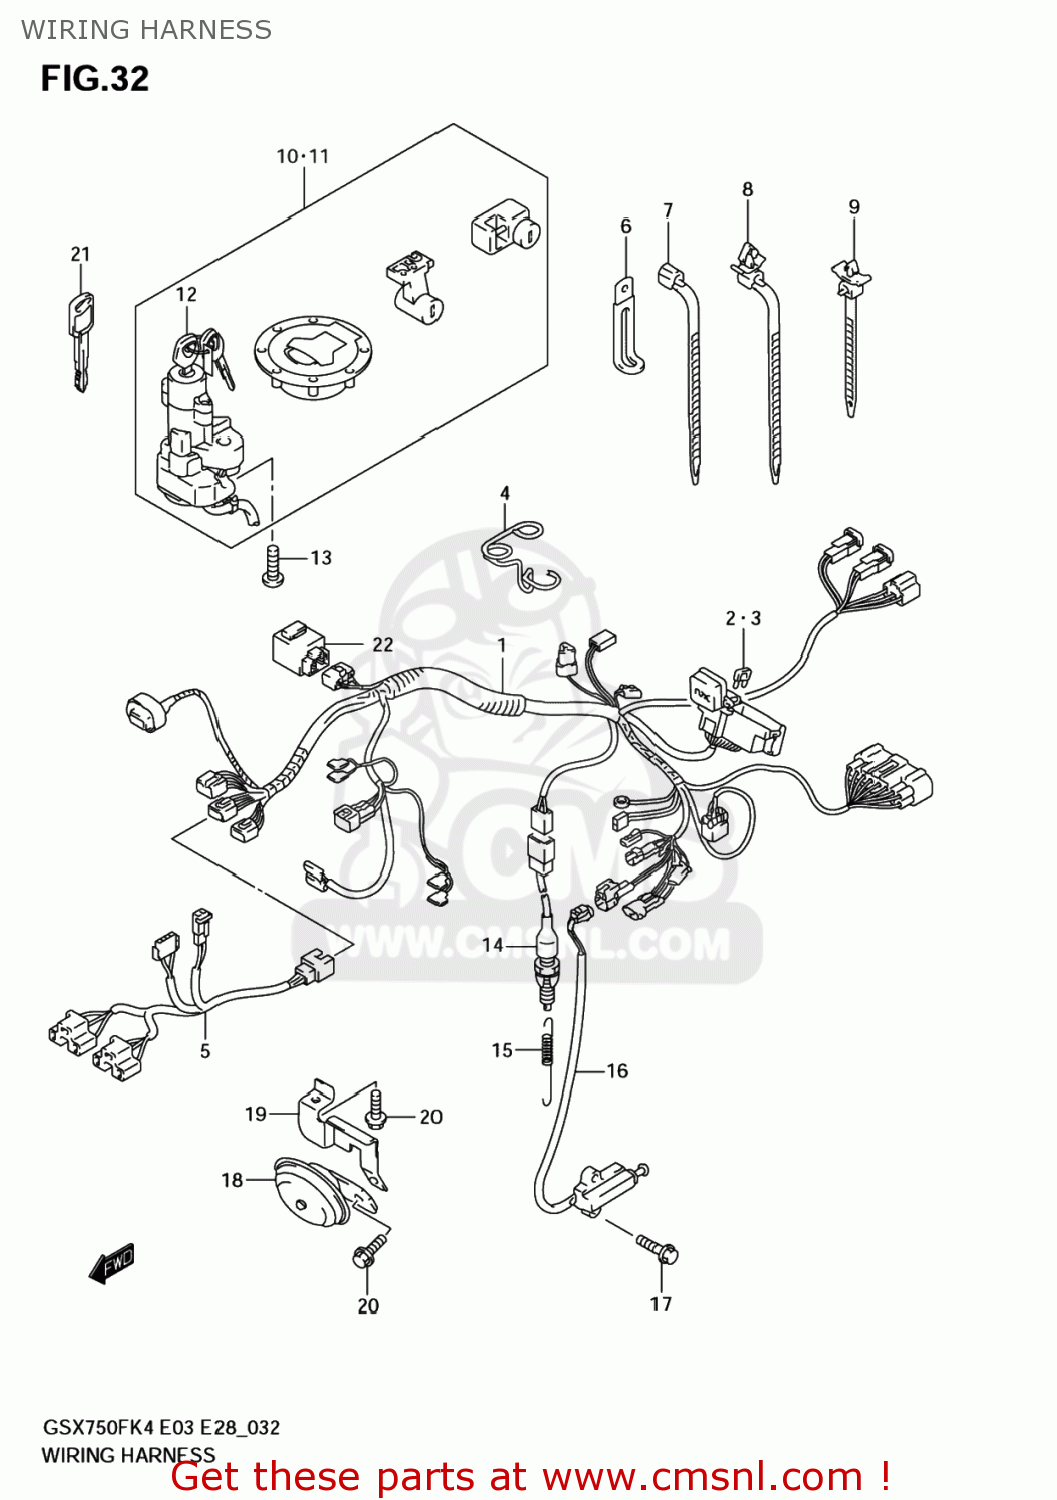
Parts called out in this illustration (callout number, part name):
1	HARNESS,WIRING
2	FUSE(10A)
3	FUSE(15A)
4	GUIDE,WIRING HARNESS
5	HARNESS,WIRING NO.2
6	WIRE,LEAD
7	CLAMP(L:135)
8	CLAMP(L:95)
9	CLAMP(L:90)
10	LOCK SET
11	LOCK SET
12	LOCK ASSY,STEE
13	BOLT(8X20)
14	SWITCH ASSY,STOP LAMP
15	SPRING
16	SWITCH ASSY,SIDE STAND
17	BOLT
18	HORN ASSY
19	BRACKET,HORN
20	BOLT
21	KEY,BLANK
22	CONTROLLER ASSY,FAN MOTOR
